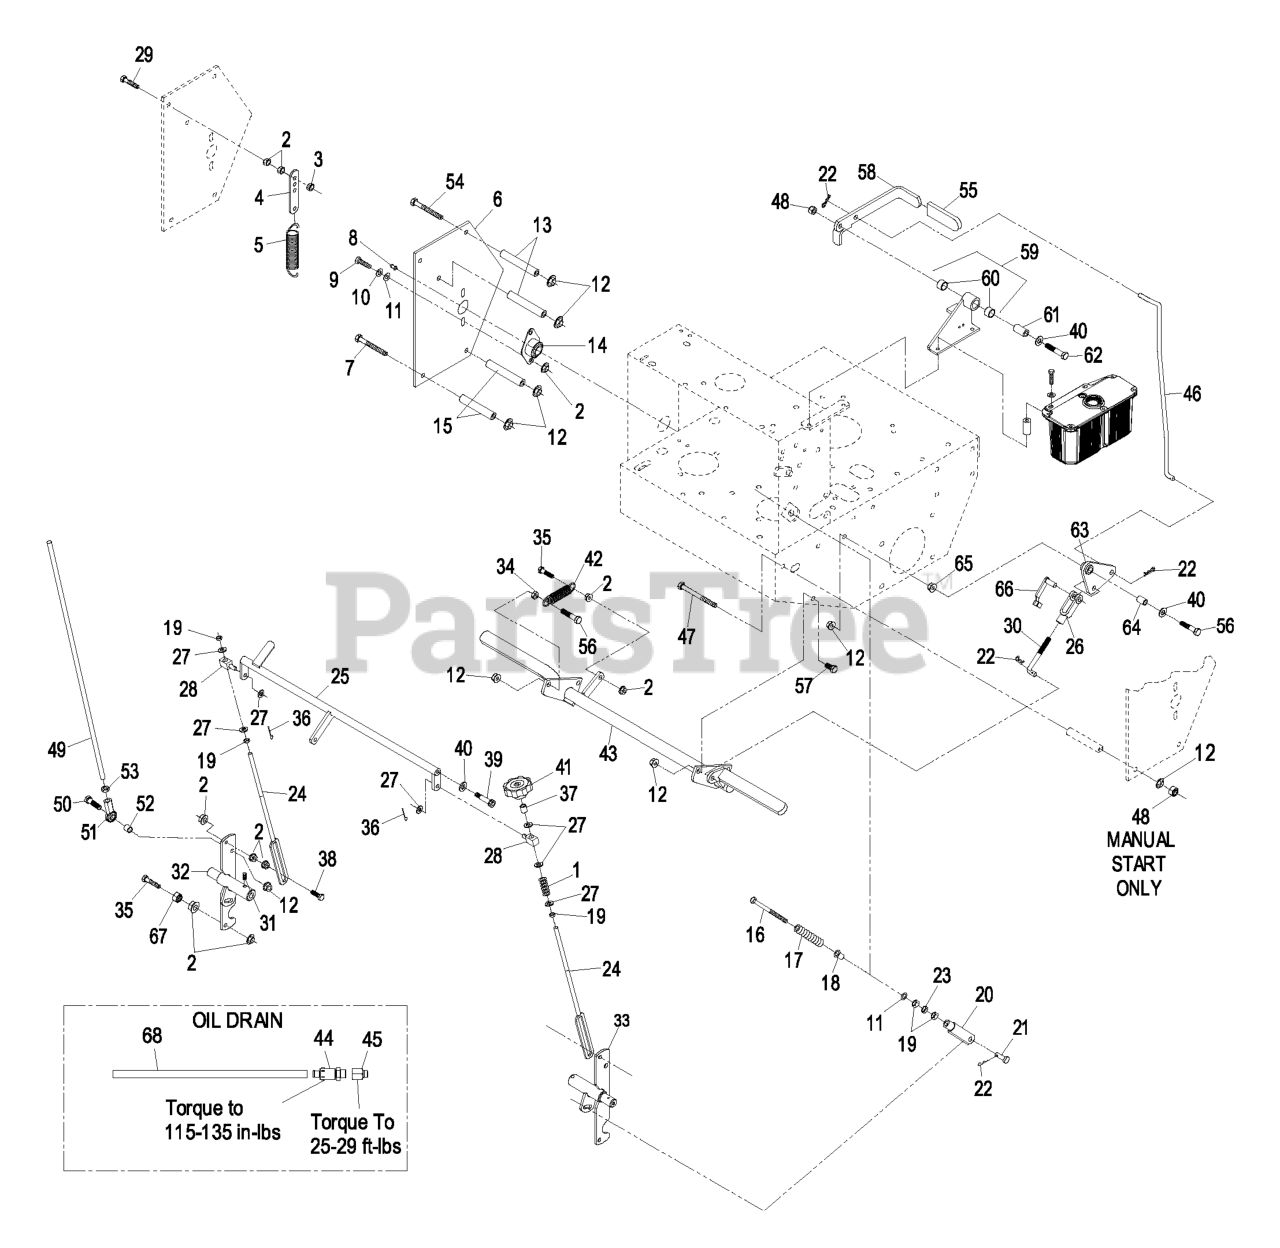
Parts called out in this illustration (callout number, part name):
1	SPRING-COMPRESSION
3	NUT-LOCK, NI
4	TAB-SPRING, EXTENSION
5	SPRING-EXTENSION
7	SCREW-HH
8	FITTING-GREASE
9	SCREW-HH
10	WASHER-LOCK
11	WASHER-FLAT
12	NUT-HHF, WHIZ
13	SPACER-SHIELD
14	BEARING-FLANGE, SIDE
15	SPACER-SHIELD
16	BOLT-RETURN, NEUTRAL
17	SPRING,COMPRESSION (NEUT)
18	BUSHING-FLANGED
19	NUT-HEX
20	YOKE-ADJUSTABLE
21	PIN-CLEVIS
22	PIN-COTTER
23	NUT-JAM
24	LINK-CONTROL, SPEED
25	CRANK-CONTROL, SPEED
26	YOKE-LINKAGE, BRAKE
27	WASHER-PLAIN
29	BOLT-TAP, HH
30	LINKAGE-LOWER
31	SCREW-SET
32	SHAFT-CONTROL, LH
33	SHAFT-CONTROL, RH
34	NUT-JAM
35	SCREW-HH
36	PIN-COTTER
38	SCREW-HH
39	SCREW-HSH
40	WASHER-FLAT
41	KNOB-TRACKING
42	SPRING-IDLER
44	VALVE-DRAIN, OIL
45	ADAPTER
46	LINKAGE,UPPER- TTHP
47	SCREW-HH
48	NUT-LOCK, NI
49	LINK,DRIVE (PLTD)
50	SCREW-HH
51	JOINT-BALL END, LH
52	SPACER-TUBE, PUMP LINK
53	NUT-HEX JAM, LH
54	SCREW-HH
55	GRIP-LEVER
56	SCREW-HH
57	SCREW-HH
58	LEVER,PARK BRK W/DECAL
59	BRACKET ASM
60	SLEEVE-BUSHING
61	BUSHING-PIVOT
62	SCREW-HH
63	BELLCRANK ASM
64	BUSHING-PLASTIC
66	PIN-SPRING, CLEVIS
67	NUT-JAM
68	TUBE-DRAIN, OIL
